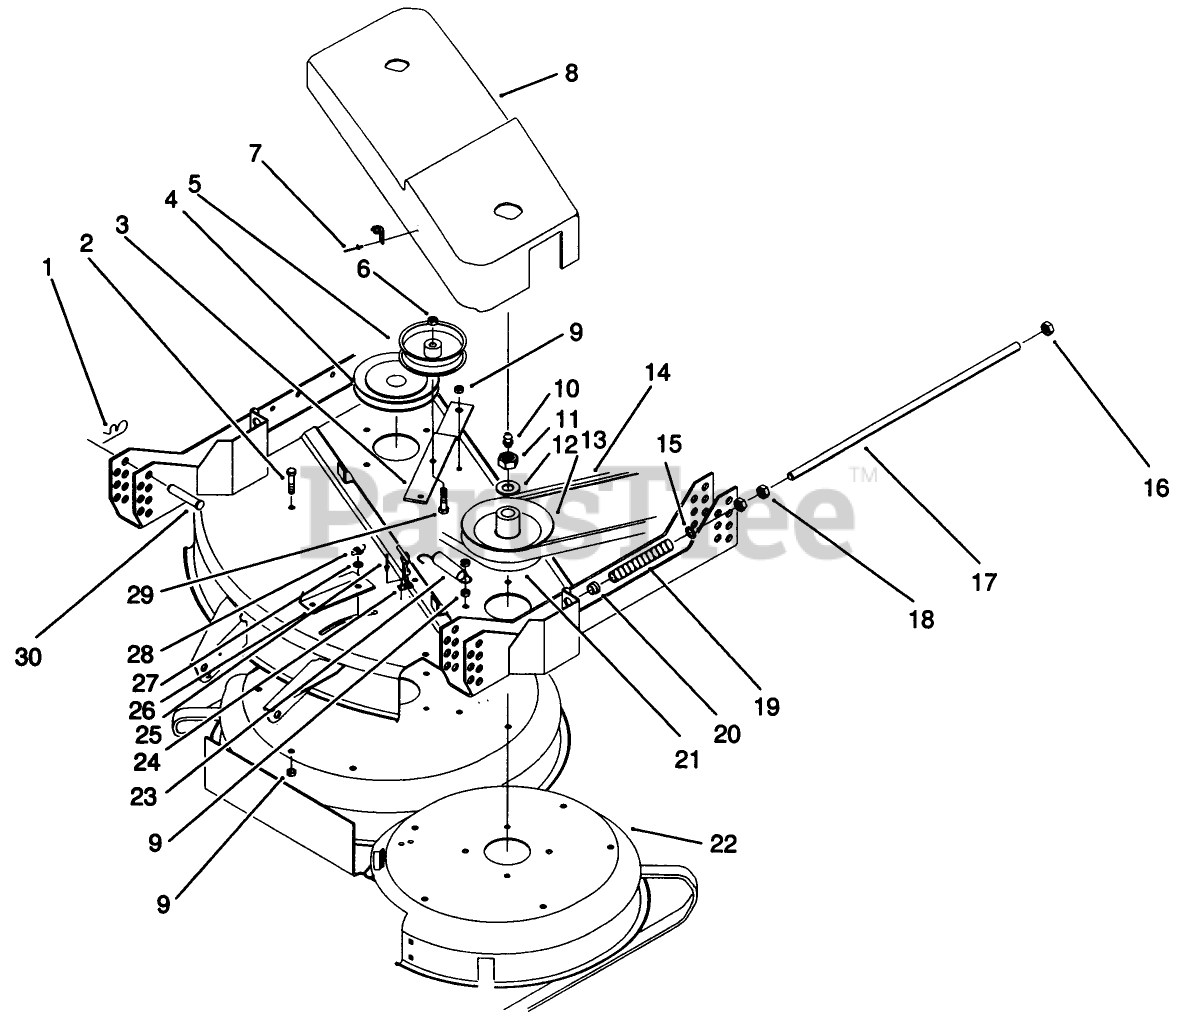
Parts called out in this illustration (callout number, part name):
1	PIN-HAIR
2	SCREW-HH
3	Lever-Idler
4	PULLEY-OUTSIDE
5	PULLEY-IDLER
6	NUT-LOCK, NI
8	COVER-PULLEY
9	NUT-LOCK, NI
10	FITTING-GREASE
11	NUT-HEX
12	WASHER
13	PULLEY-CENTER
14	V-BELT, DECK DRIVE
15	WASHER
16	NUT-LOCK, NI
17	SHAFT-ADJUSTING
18	NUT-JAM
19	SPRING
20	BUSHING-FLANGE
21	V-BELT, DECK
22	Deck W.A. (Incl. Ref. #3, & 33 on Page 1)
23	SPRING-EXTENSION, DECK
24	ASSY-FLEX DRAW LATCH
25	RIVET-POP
26	Cover-Slot
27	WASHER-LOCK
28	NUT-WING
29	SCREW-HH
30	PIN-CLEVIS
